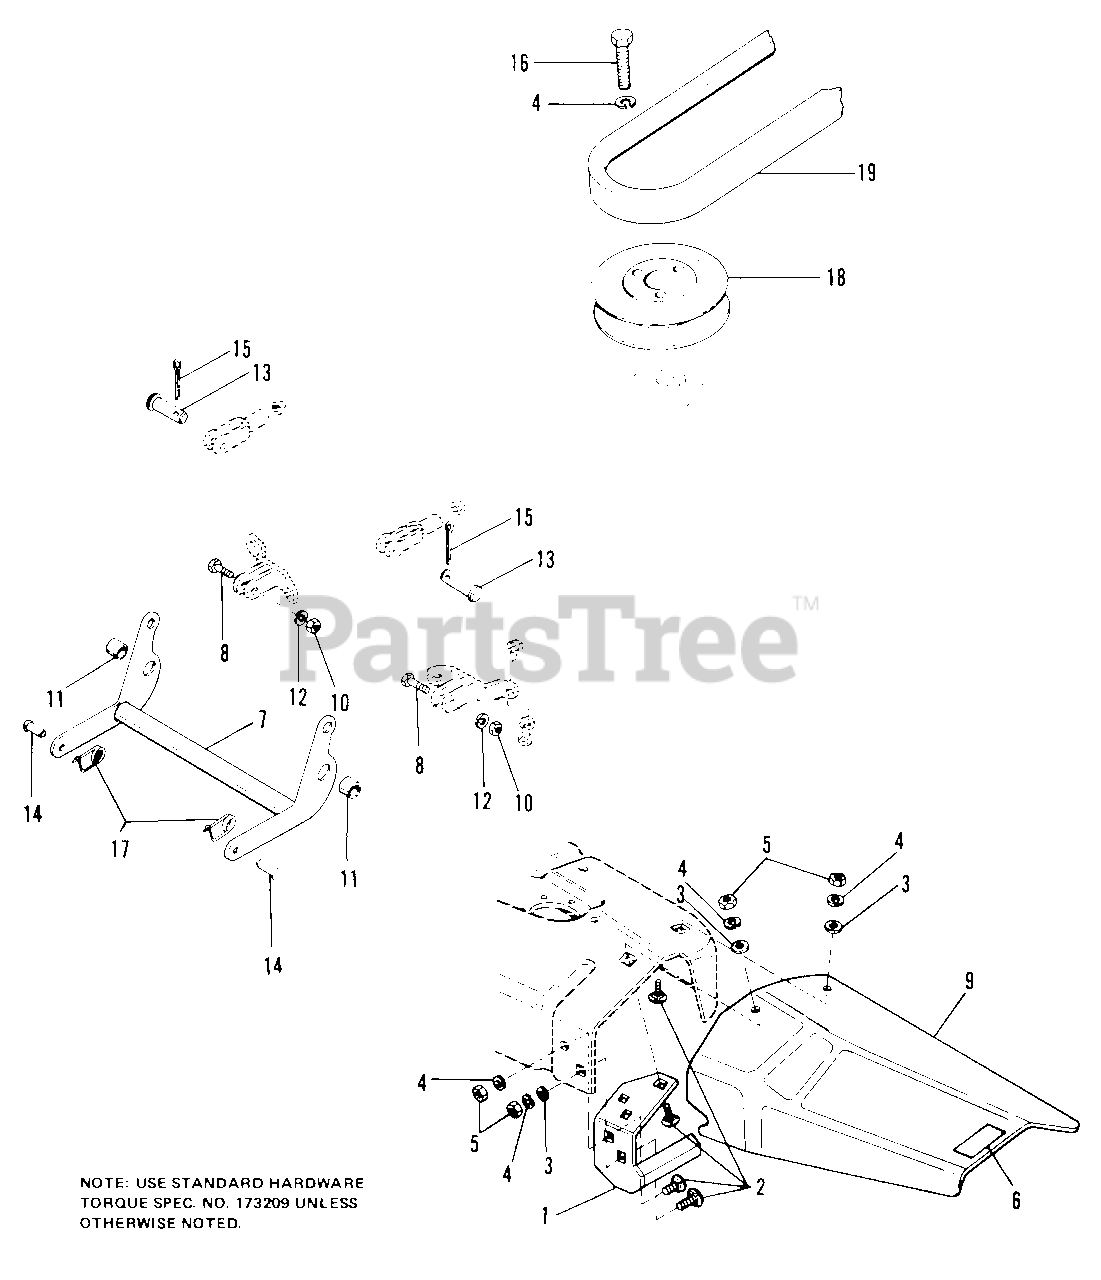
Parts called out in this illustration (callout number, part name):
1	GUARD ASSY, Stone
2	BOLT, Rd. Hd., 3/8-16 x 1-1/4
3	WASHER, Special
4	LOCKWASHER, Spring, 3/8
5	NUT, Hex, 3/8-16
6	DECAL, Danger
7	ARM ASSY, Rocker
8	CAPSCREW, Hex Hd., 1/2-13 x 1-1/4
10	NUT, Hex, 1/2-13
12	LOCKWASHER, Spring, 1/2
13	PIN, Yoke
14	PIN,
15	PIN, Cotter, 1/8 x 1
16	CAPSCREW, Hex Hd., 3/8-16 x 1-3/4, Gr. 8
17	CLIP, Safety Pin
19	BELT, "V", Tractor to Mower
